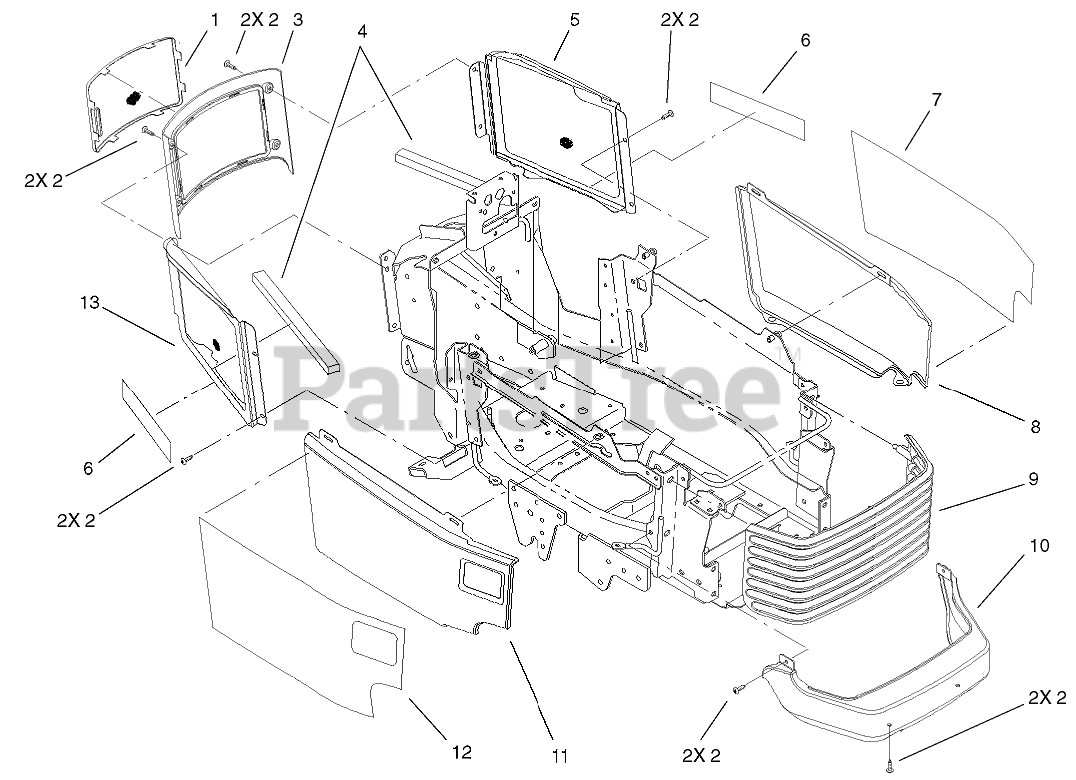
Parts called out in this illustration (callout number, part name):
1	SCREEN-REAR
2	SCREW-HH
3	COVER-REAR
4	FOAM-SEAL, SIDE SCREEN
5	Cover-Side LH
6	Decal-18gt (only on: 73471)
6	Decal-20gt (only on: 73542, 73570)
7	DECAL - HOOD LH
8	PANEL-SIDE, LH HOOD
9	GRILL
10	COVER-BUMPER
11	PANEL-SIDE, RH HOOD
12	DECAL - HOOD RH
13	Cover-Side, RH
